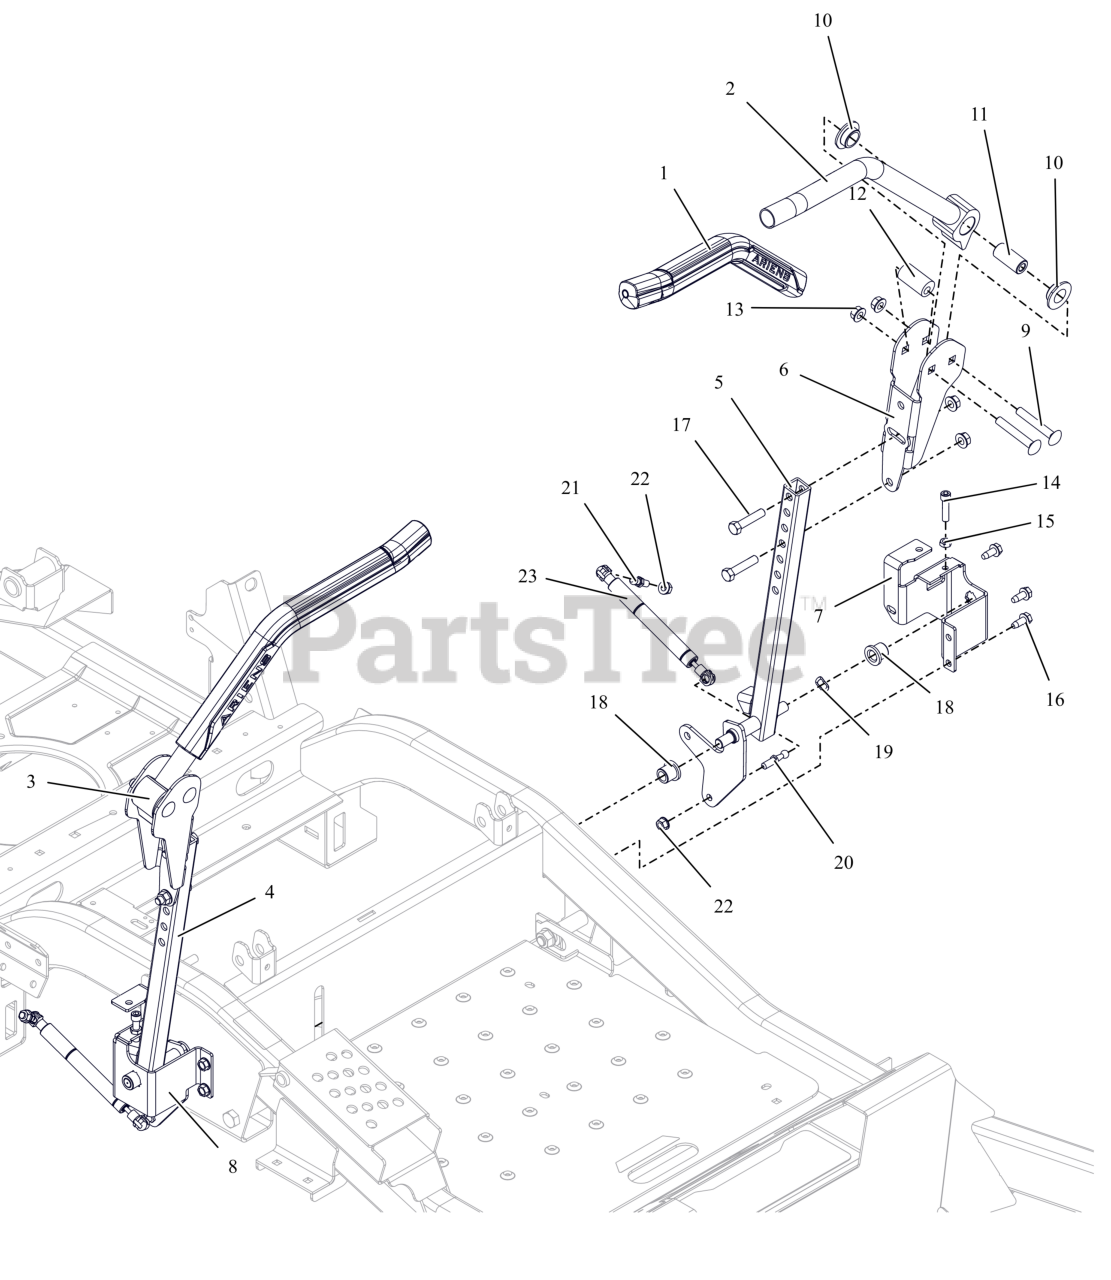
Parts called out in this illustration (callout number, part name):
1	GRIP- HANDLEBAR ARIENS
2	WLDMT, CONTROL HANDLE-LH (BLACK)
3	WLDMT, CONTROL HANDLE-RH (BLACK)
4	WLDMT, STEERING RH
5	WLDMT, STEERING LH
6	ADJ UPPER CONTROL ARM BRKT-BLK
7	BRKT- STEERING ARM MOUNT - LH
8	BRKT- STEERING ARM MOUNT - RH
9	BLT, RHSSN.38-16X2.50 G5 ZCC
10	BSHG-FLG .762X1.48X.44 IGLIDER
11	SPACER, STEERING ARM
12	BSHG, ECCENTRIC.406X.875X1.625
13	NUT-LK-TOP-FLG .38-16 ZC120
14	BLT, SHCS .312-18X1.25 G8 SS
15	NUT-JAM .312-18 G2 ZCC
16	SCR,TAP .312-18X.75 HWH TR ZCC
17	BLT, HEX .38-16X1.75 G5 ZCC
18	BHSG-FLG .500X.750X.750X.125
19	WAVE WASHER .531X.781X.125FH
20	STUD-BALL-THREADED
21	STUD- BALL
22	NUT,LK-CTR-FLG .31-18 GF ZCC
